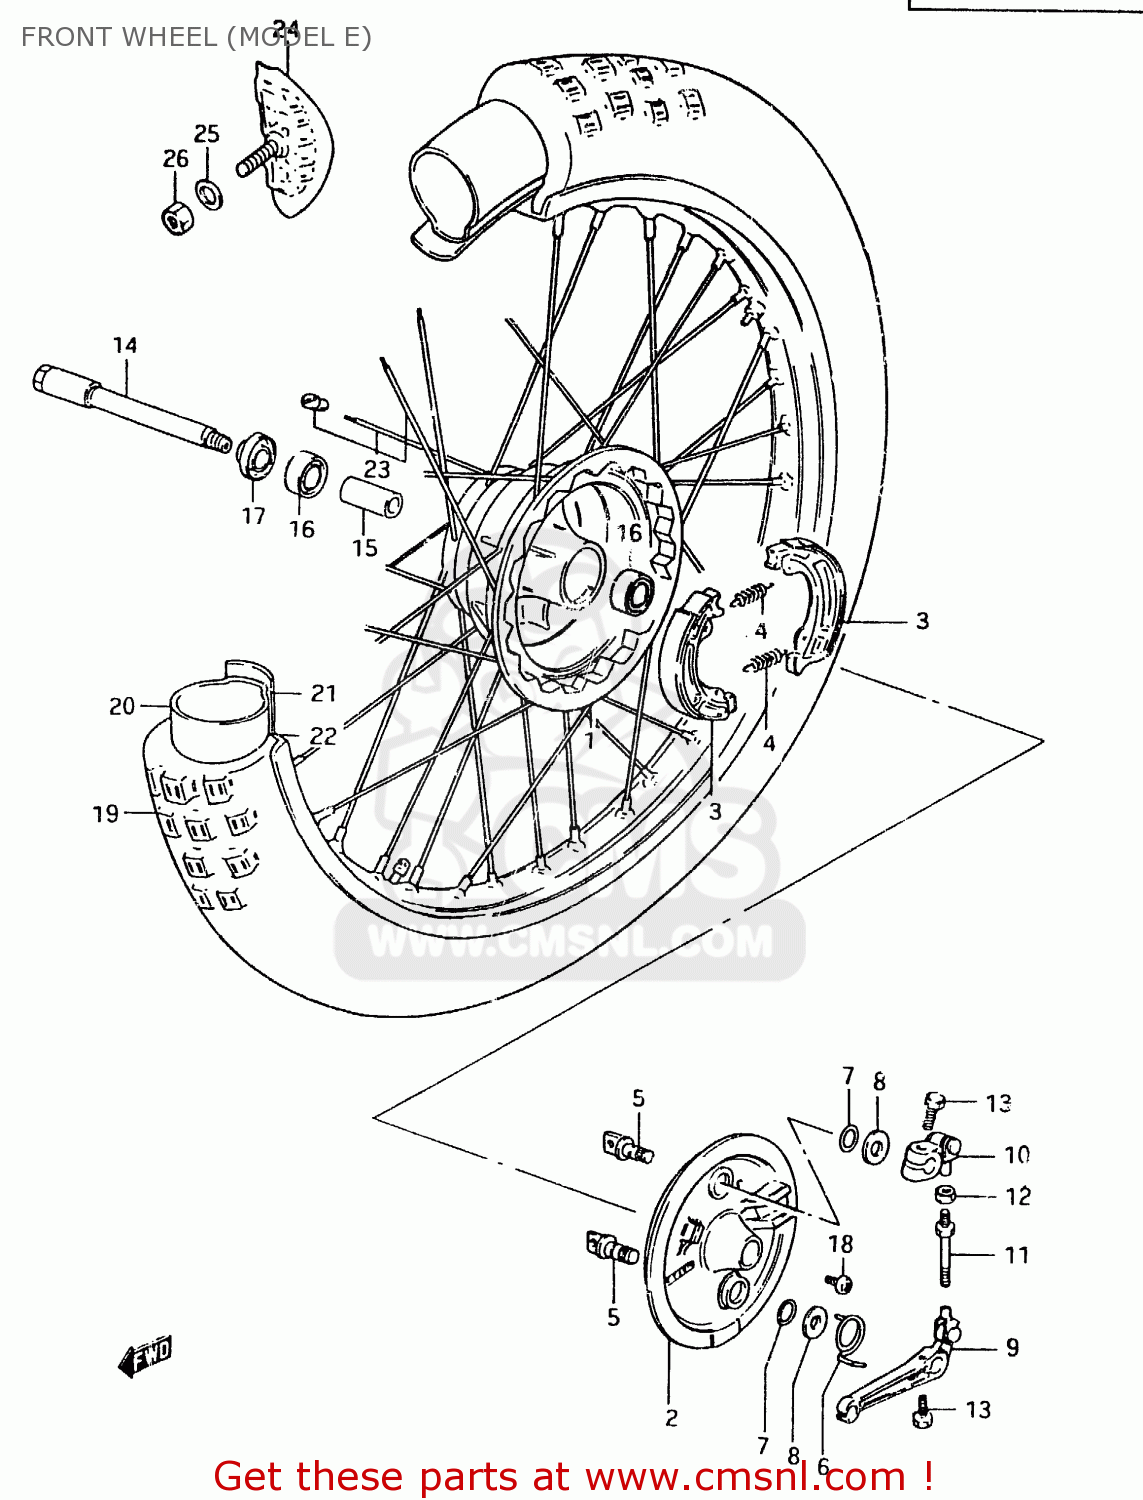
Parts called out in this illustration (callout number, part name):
1	DRUM,FRONT HUB
2	PANEL,FRONT HUB
3	SHOE,BRAKE (MCA)
4	SPRING
5	CAM,FRONT BRAKE
6	SPRING
7	O-RING (D:2 ID13.8)
8	WASHER (14.2X22X1)
9	SHOE SET,BRAKE
10	LEVER ASSY, BRAKE CAM, NO.2
11	ROD,BRAKE CAM LEVER CONNECTION
12	NUT 6MM
13	BOLT
14	AXLE,FRONT
15	SPACER,FRONT HUB BEARING
16	BALL BEARING 15X35X11
17	SPACER,FRONT AXLE,RIGHT
18	SCREW
19	TIRE,FRONT
20	TUBE,INNER
21	PROTECTOR,WHEEL,INNER
22	RIM,FRONT WHEEL (1.60X21)
23	SPOKE SET,FRONT
24	STOPPER,BEAD
25	WASHER
26	NUT 8MM
